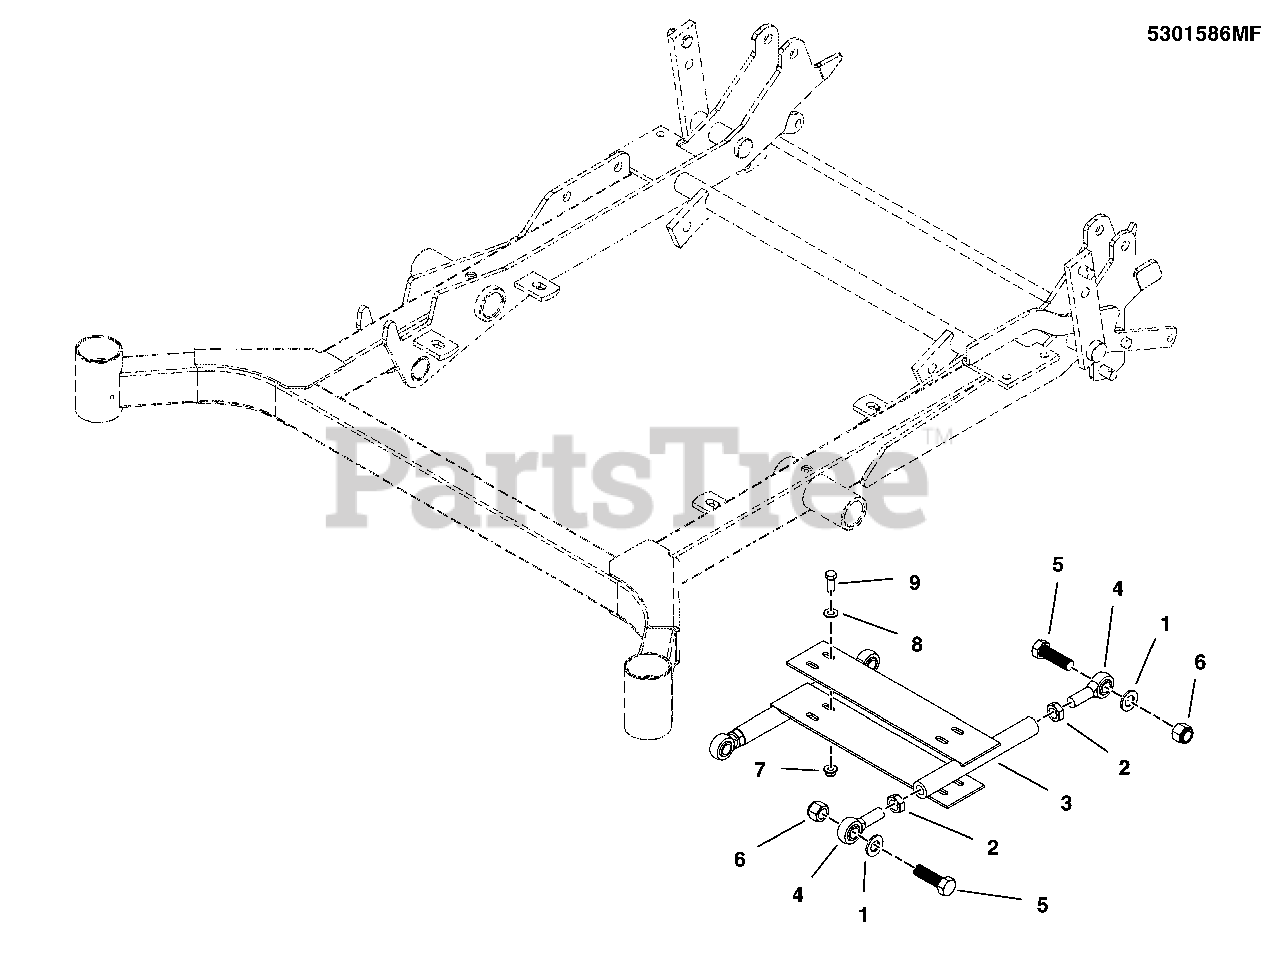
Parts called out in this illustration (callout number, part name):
1	WASHER, 5/8 SAE
2	NUT, 5/8-18, HEX JAM
3	WELD, DECK STABILIZER - RED
4	BALL JOINT, 5/8-18, MALE
5	BOLT, HEX, 5/8-11 X 21/2, GD5, CZ
6	NUT, 5/8-11 HEX NYLON LOCK
7	NUT, 3/8-16 HEX SERRATED FLANGE
8	WASHER, 3/8 SAE
9	BOLT, 3/8-16 X 1 GD5 YZ
